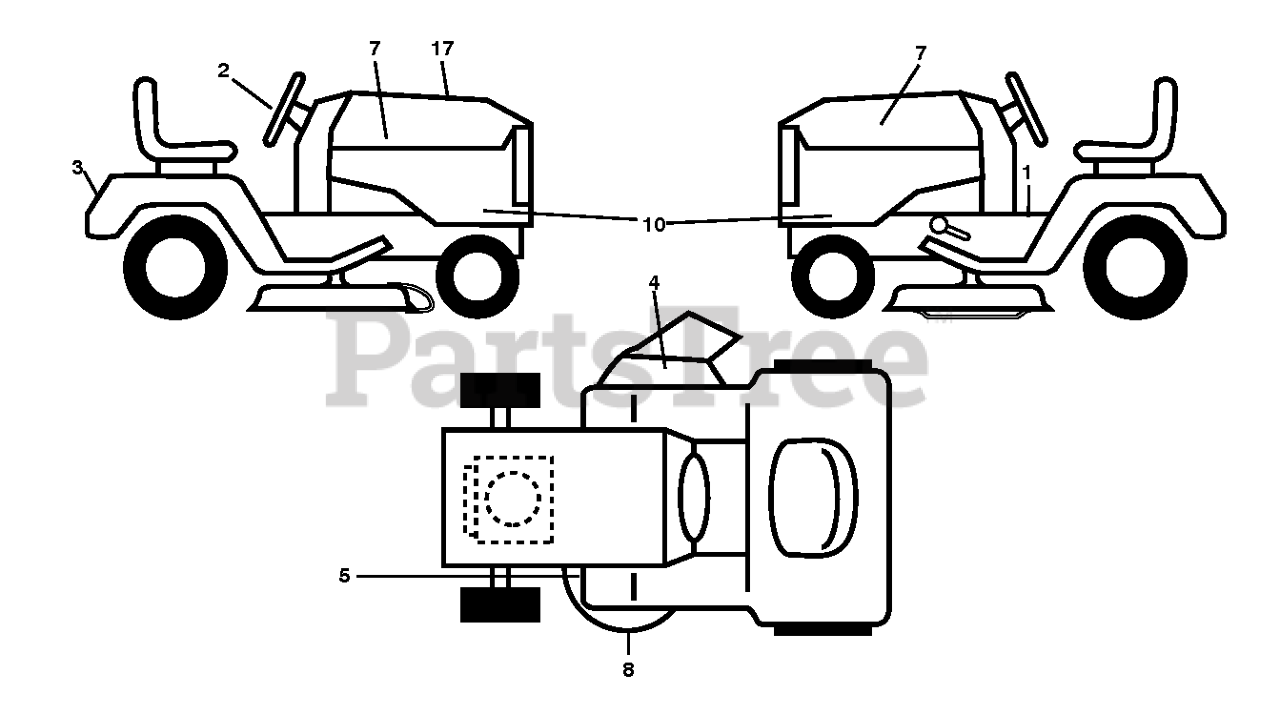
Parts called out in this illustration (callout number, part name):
1	DECAL.FENDER.WARNING.ENGLISH
2	DECAL.STRWHL.STDSQ.PPRO.BLK09
3	DECAL.REARFNDR.LOGO.BLK.2017
4	DECAL, DECK DEFLECTOR, WARNING
5	DECAL.V-BELT.SCH.42/46"MEC/ELE
7	DECAL.POULAN PRO.YEL/BLK.2017
8	DECAL DECK DECAL STEELGUARD_LI
10	DECAL TRACTOR SIDE PANEL DECAL
17	DECAL DECAL.RPL.LCC.608.TLW.46
